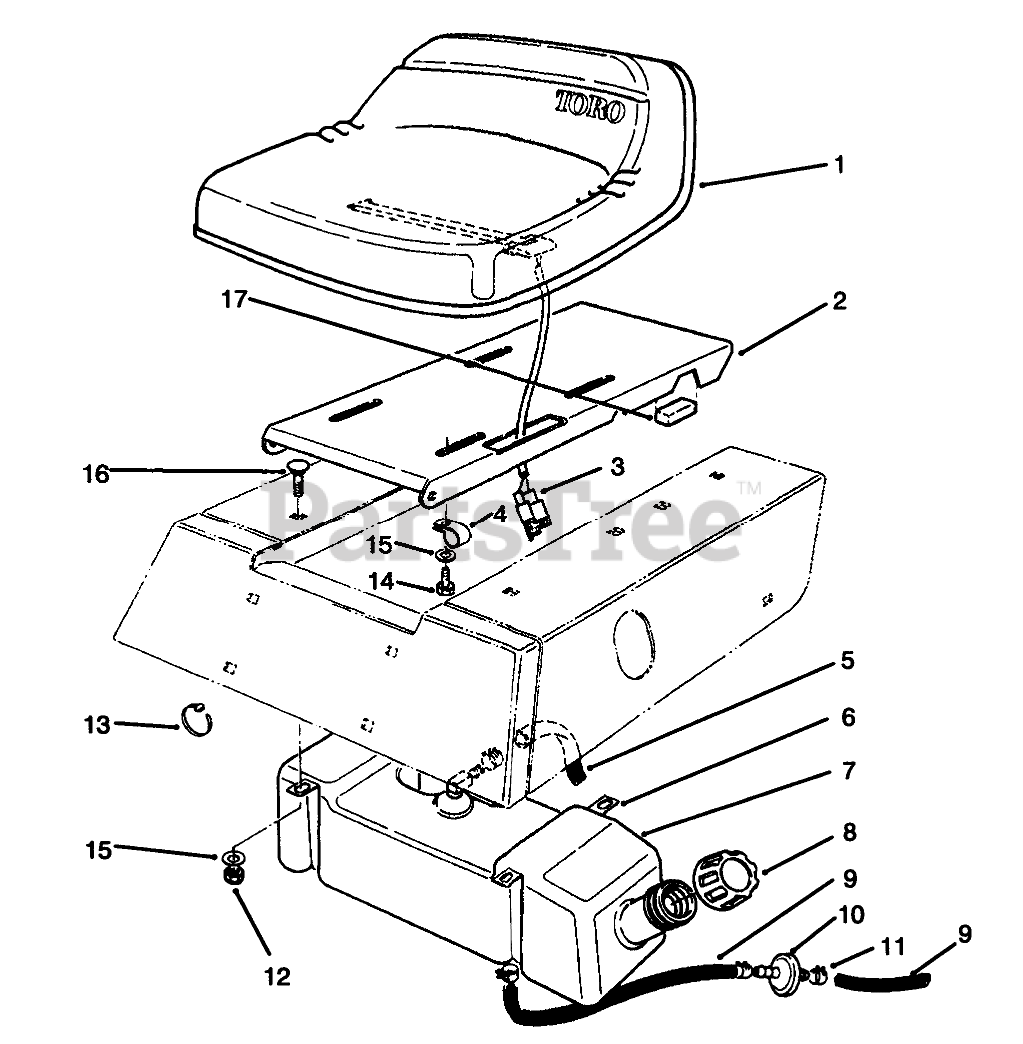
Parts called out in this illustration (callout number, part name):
1	Seat
2	Base-Seat
3	SWITCH-SEAT
4	CLIP-FUEL LINE
5	HOSE-FUEL
6	STRAP-GAS TANK
7	TANK-GAS
8	GAS CAP ASM
9	HOSE-FUEL
10	FILTER-FUEL
11	CLAMP-HOSE
12	NUT-LOCK, NI
13	TIE-CABLE
14	SCREW-HH
15	WASHER-PLAIN
16	SCREW-CARR
17	PAD-ISOLATOR
